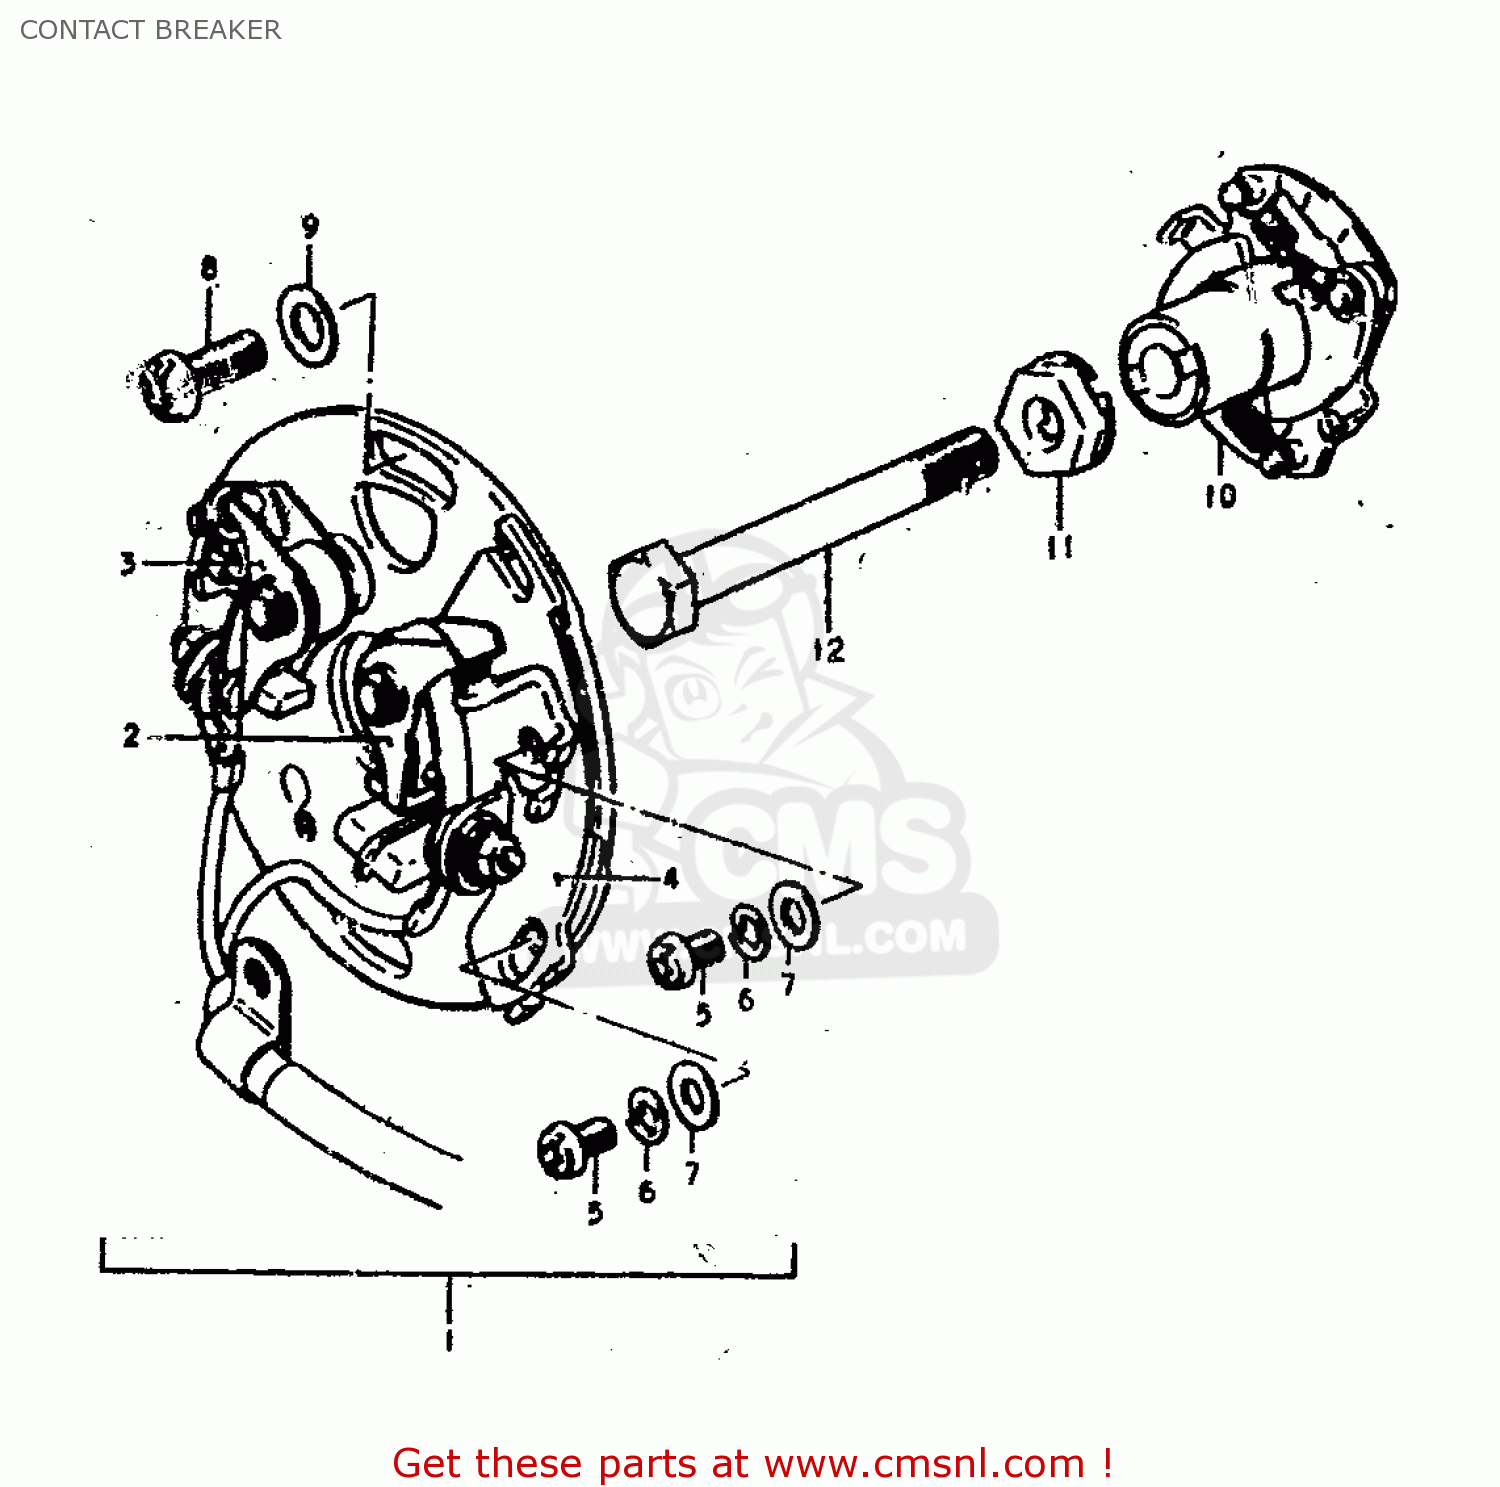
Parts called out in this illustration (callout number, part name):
1	BREAKER ASSY,CONTACT
2	POINT ASSEMBLY,CONTACT,RIGHT
3	POINT ASSEMBLY,CONTACT,LEFT
4	PLATE,CONTACT POINT
5	SCREW(4X10)
6	LOCK WASHER
7	WASHER
8	SCREW(5X12)
9	WASHER 5MM
10	GOVERNOR ASSEMBLY
11	WASHER
12	BOLT
